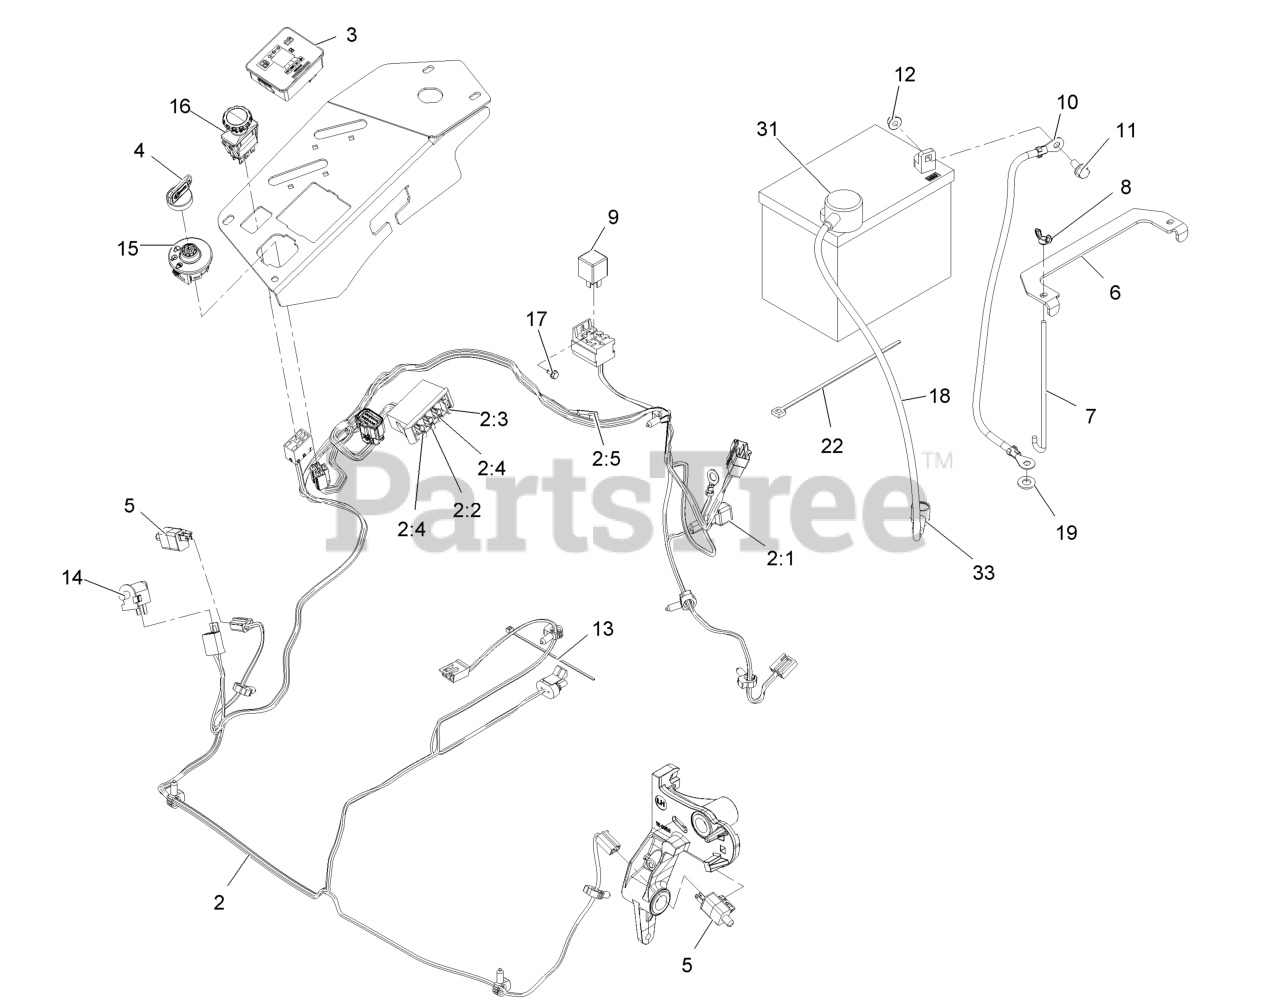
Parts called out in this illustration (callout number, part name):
2:2	FUSE-BLADE, 10 AMP
2:3	FUSE-BLADE, 15 AMP
2:4	FUSE-BLADE, 25 AMP
2:5	CAP-PLUG
3	FUEL/HOUR METER ASM
4	KEYS-IGNITION (SPARE PAIR
4	KEY-IGNITION
6	STRAP-TIE DOWN, BATTERY
7	BOLT-HOLDDOWN
8	WINGNUT
10	CABLE-BATTERY, NEGATIVE
11	SCREW-HHF
12	NUT-HF, NI
13	TIE-CABLE
14	SWITCH-BAIL
16	SWITCH-PTO, 10 AMP
17	SCREW-HWH
18	CABLE-BATTERY, POSITIVE
19	WASHER-FLAT
22	TIE-PLASTIC
31	INSULATOR-BATTERY
33	INSULATOR-SOLENOID
